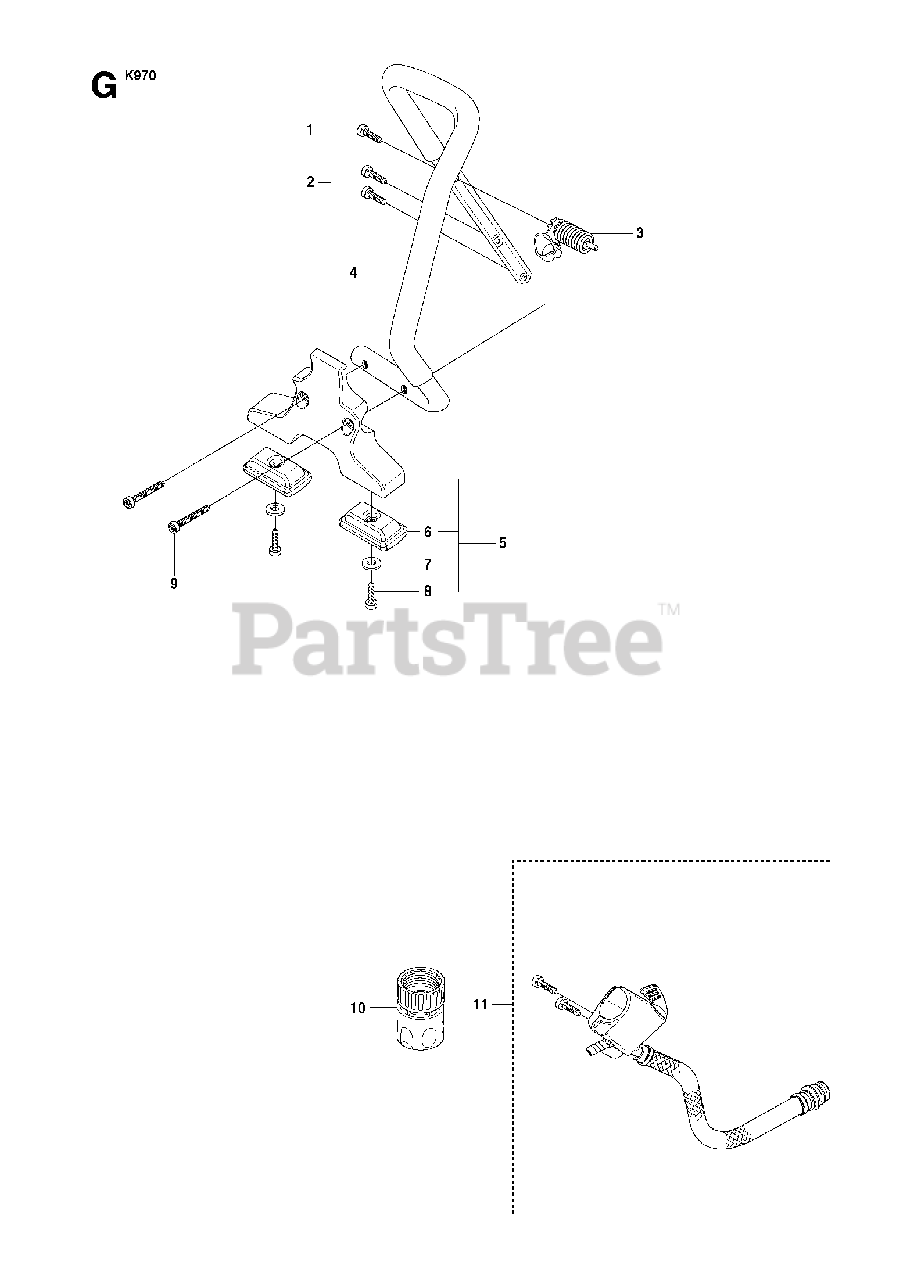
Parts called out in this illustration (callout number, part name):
1	SCREW ITXSCM
2	SCREW ITXSCT
3	ANTIVIBRATION ELEMENT
5	GROUND SUPPORT
8	SCREW ITXSCM
9	SCREW ITXSCT
